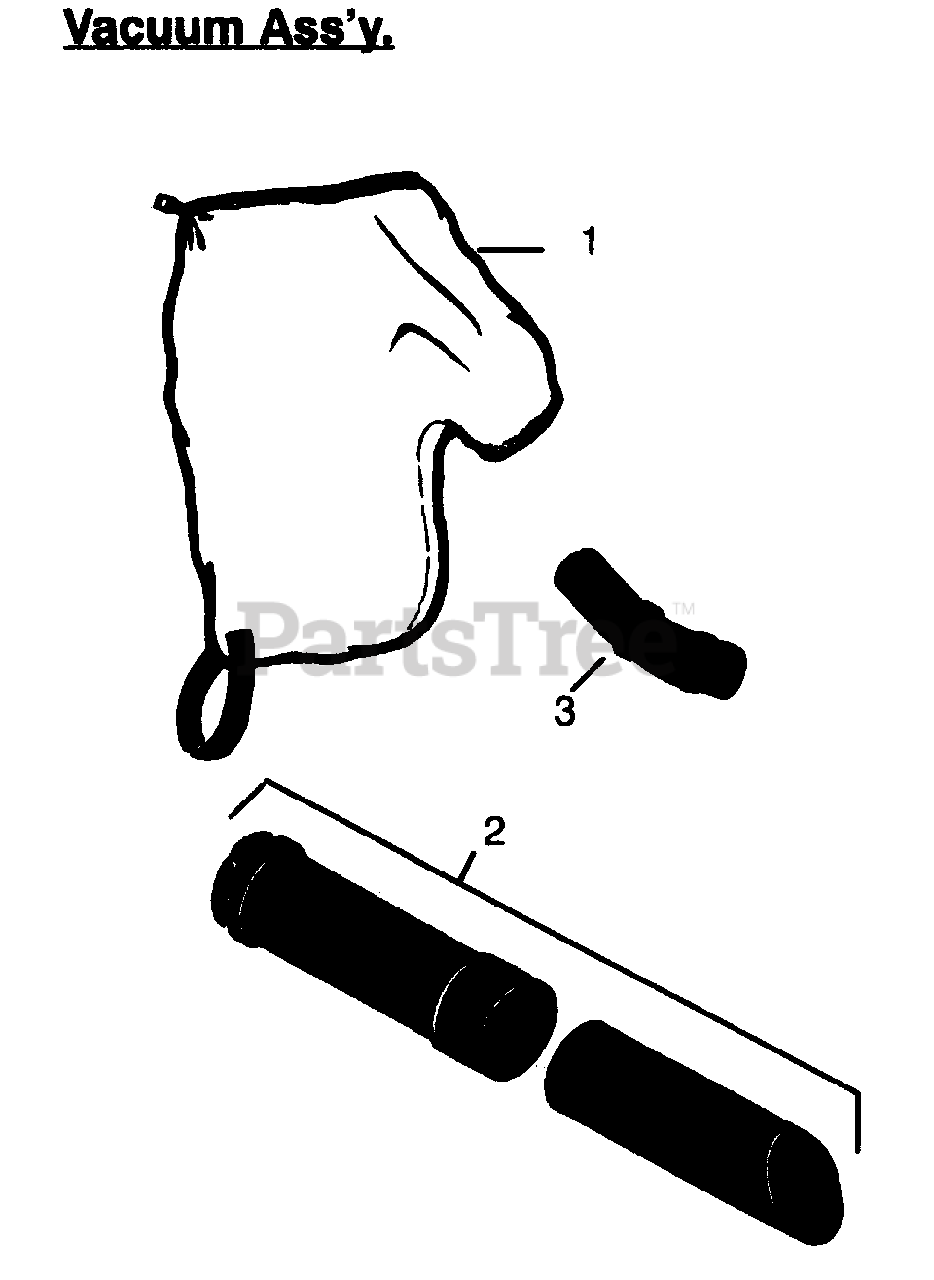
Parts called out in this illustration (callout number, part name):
1	Collection Bag
2	Vacuum Tubes
3	Vacuum Elbow
